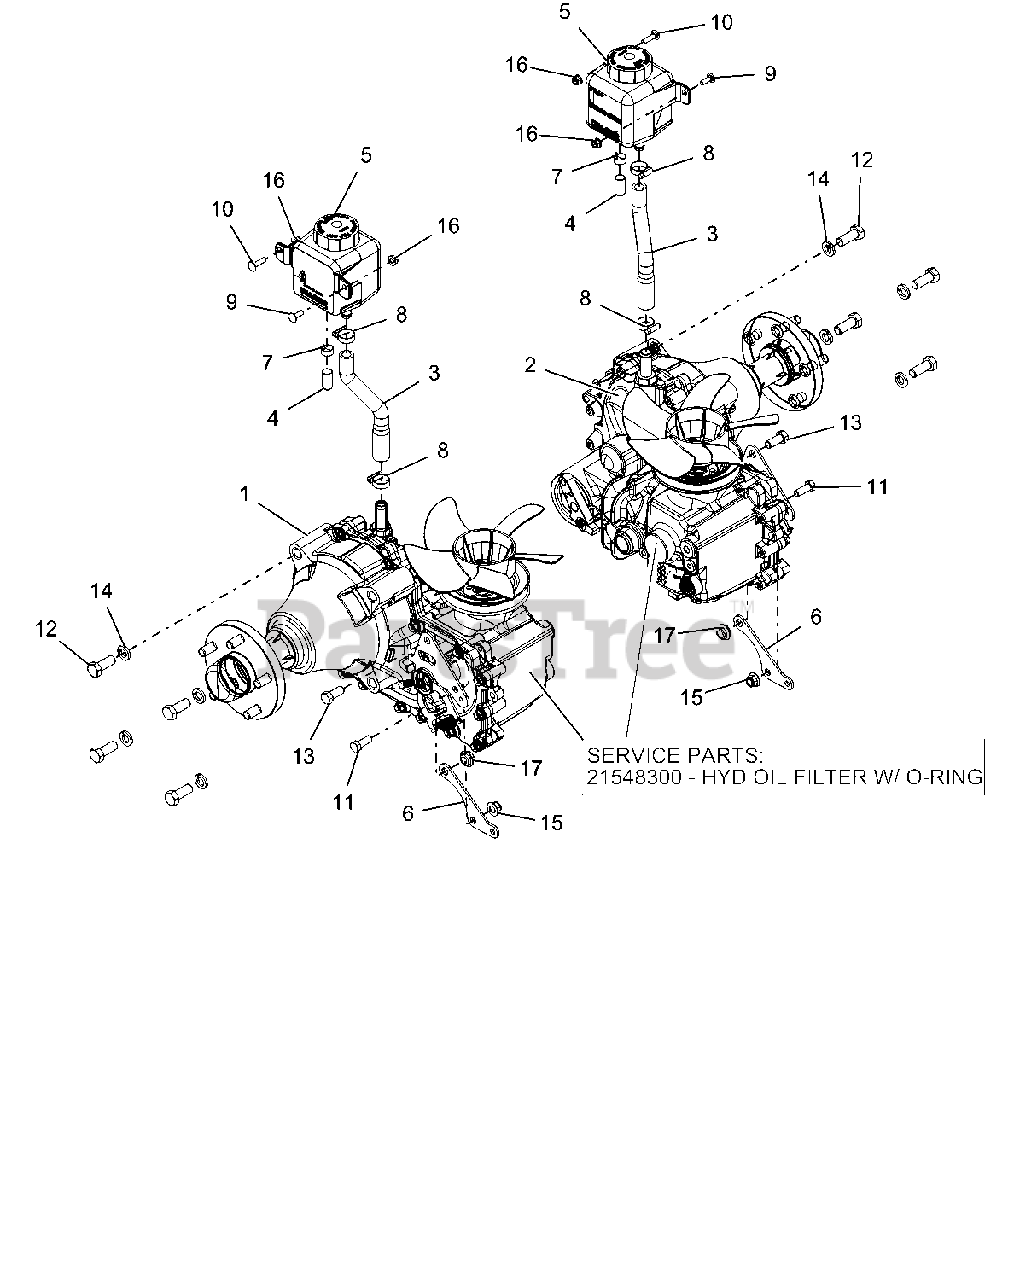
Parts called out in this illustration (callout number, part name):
1	TRANS, RH HG ZT-5400
2	TRANS, LH HG ZT-5400
3	HOSE,PT200/400 TRANS OVERFLOW
4	CAP, .50 BARBED FITTING
5	TANK, HYDRO OVERFLOW 700 ML
6	BRKT,DRIVE CONTROL LINKAGE MTG
7	CLAMP, .62 SPRING
8	CLAMP,.88 DIA. HOSE
9	BLT-RDHDSQNK .25-20X.75 G5YZ
10	@BLT-RDHDSQNK .25-20X1.00 G5YZ
11	@BLT-HEX .38-16X1.00 GR5 YWZC
12	@BLT-HEX .50-13X1.25 GR5 YWZC
13	@BLT-HEX .44-14X1.00 GR5 YWZC
14	@WSHR-LK .50X.125 REG YWZC
15	@NUT-LK-NYL-FLG .38-16 YWZC
16	@NUT-LK-NYL-FLG .25-20 YWZC
17	@NUT-LK-NYL-FLG .44-14 YWZC
18	FILTER,HYD OIL W/ORING ZT-54OO
